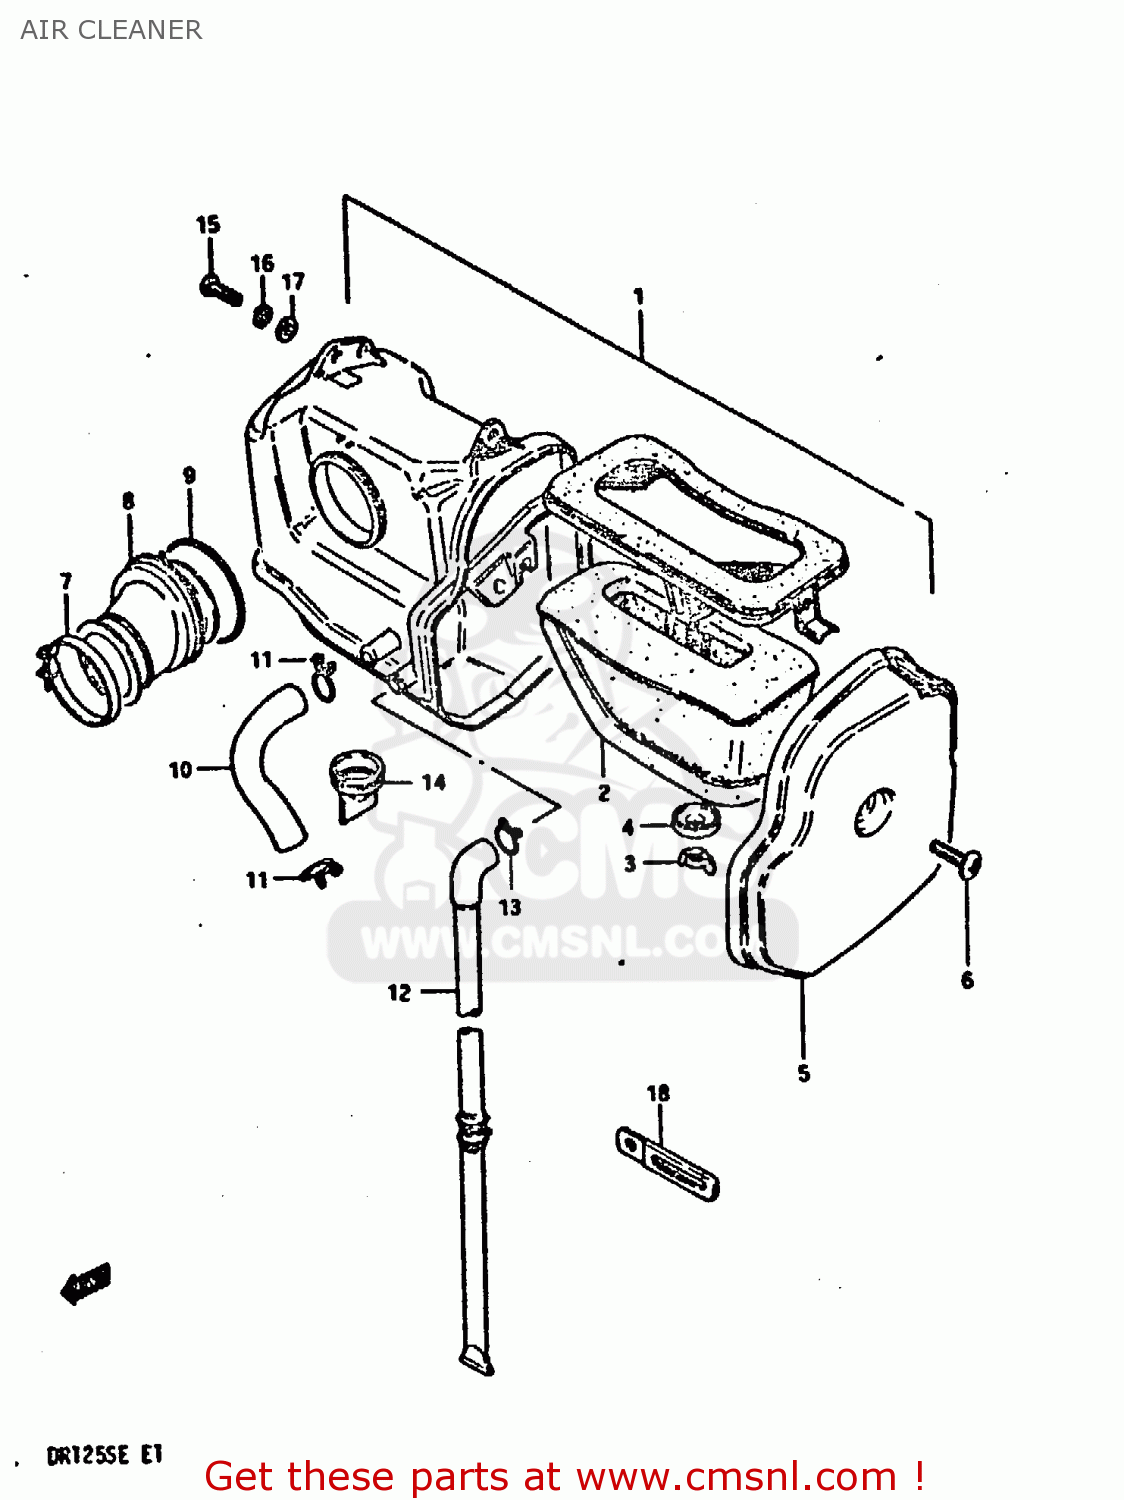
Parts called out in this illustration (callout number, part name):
1	CLEANER ASSEMBLY,AIR
2	ELEMENT,AIR CLEANER
3	NUT
4	WASHER
5	CAP
6	SCREW, COVER SIDE
7	CLAMP
8	TUBE,OUTLET
9	CLAMP,CLEANER SIDE
10	TUBE,AIR CLEANER BREATER
11	CLAMP
12	HOSE,AIR CLEANER DRAIN
13	CLAMP
14	DRAIN TUBE
15	BOLT, UPPER
16	LOCK WASHER
17	WASHER
18	CLAMP
